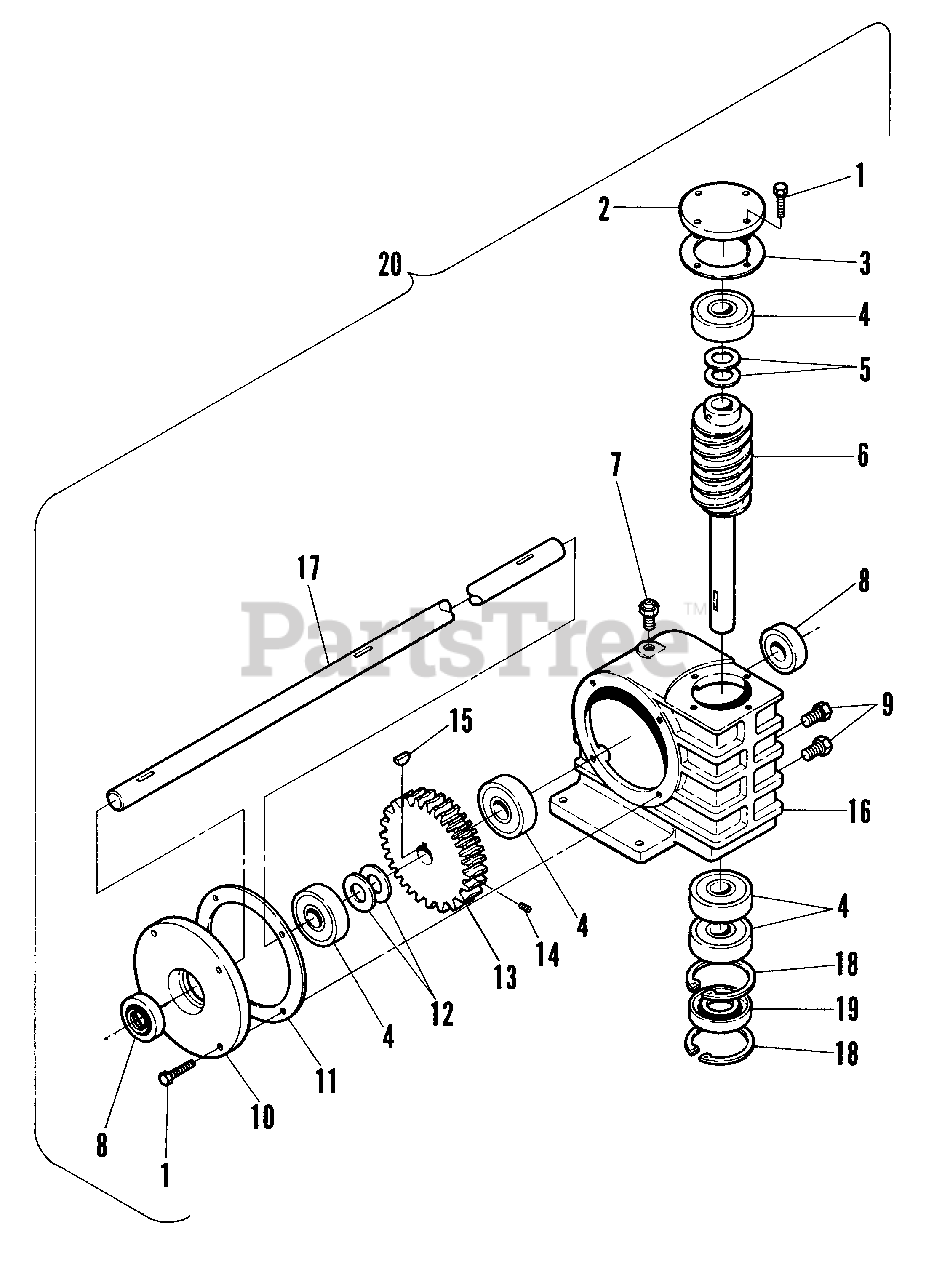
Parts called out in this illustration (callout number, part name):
1	1/4 - 20 x 5/8 Hex Hd. Cap Screw
2	INPUT COVER, w/Brg. (P/N 77324)
3	INPUT GASKET
4	BEARING
5	SHIMS, 5/8 x 7/8 x .010
6	WORM, Assembly
7	BREATHER
8	SEAL, Output Shaft
9	PIPE PLUG 1/8 - 27
10	OUTPUT COVER w/Brg. (P/N 77324)
11	OUTPUT GASKET
12	SHIMS, 5/8 x 7/8 x .005
14	1/4 - 20 x 3/8 Set Screw
15	5/405 Woodruff Key
16	GEAR CASE
17	OUTPUT SHAFT
18	SNAP RING
19	SEAL, Input
20	GEARBOX, Complete Assembly
